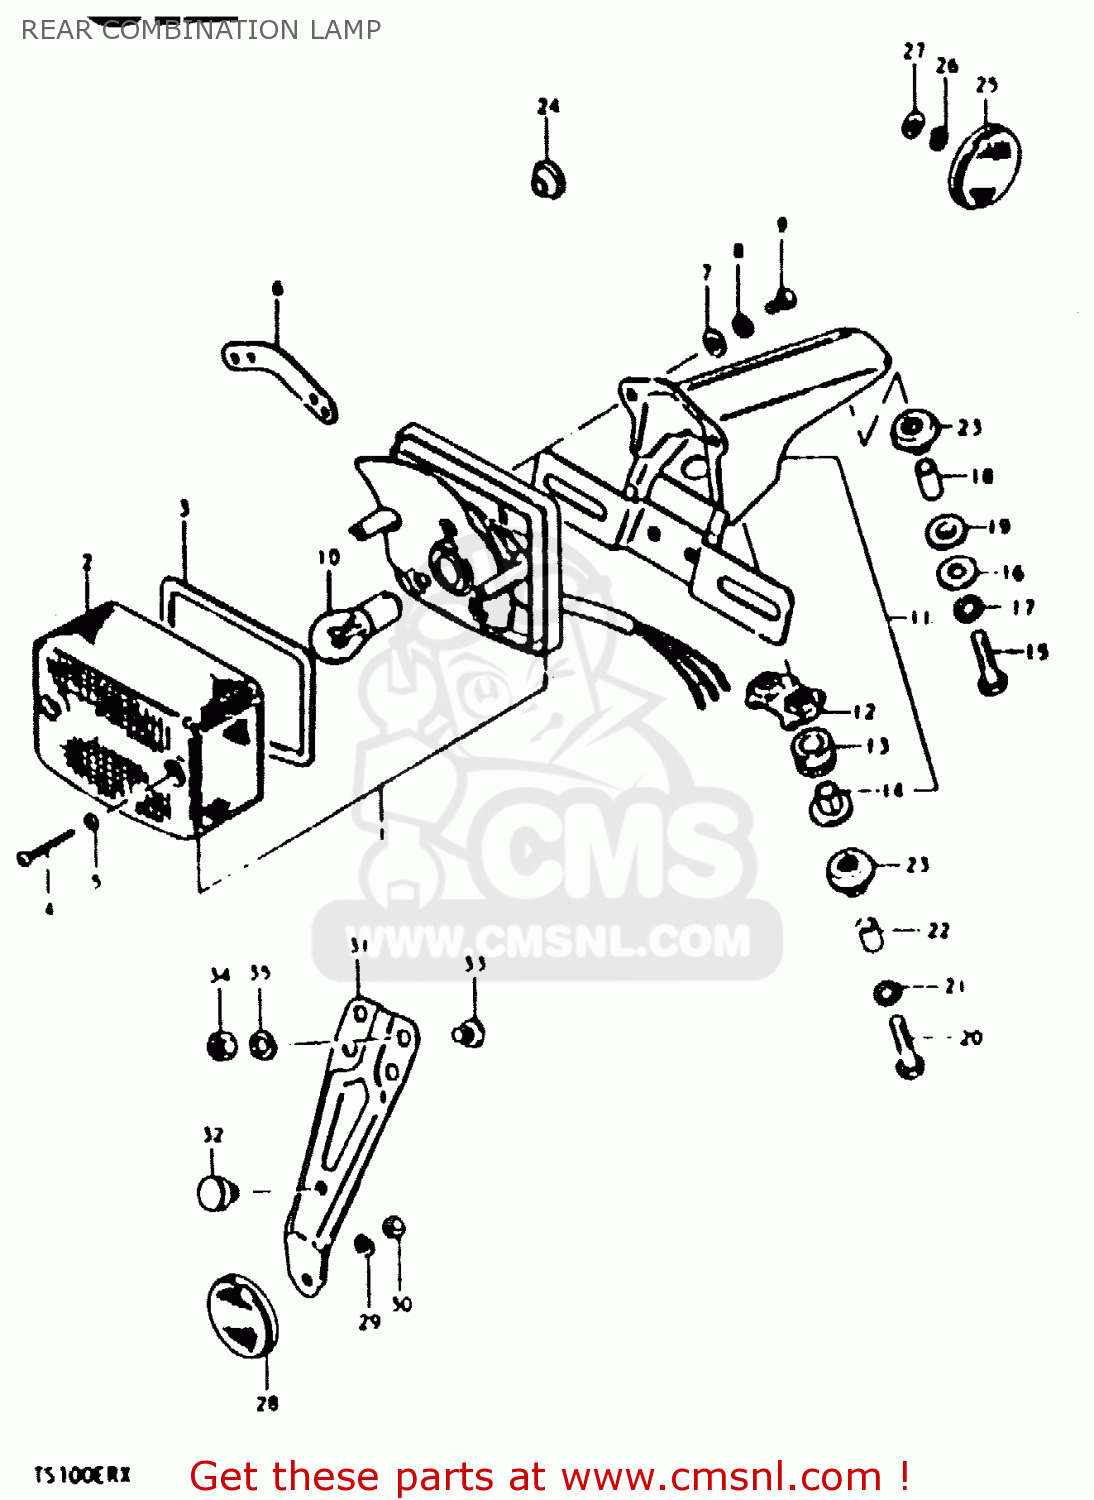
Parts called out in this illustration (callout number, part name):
1	LAMP UNIT,REAR COMBINATION
2	LENS
3	GASKET (NAS)
4	BOLT
5	GASKET (NAS)
6	PLATE,REAR COMBINATION LAMP
7	WASHER
8	LOCK WASHER
9	SCREW
10	BULB(6V10/3W,STANLEY,A4854H)
11	BRACKET UNIT,TAIL LAMP
12	PLATE
13	CUSHION
14	SPACER
15	BOLT
16	WASHER (6.5X20X1.2)
17	LOCK WASHER
18	SPACER
19	CUSHION
20	BOLT 6X40
21	LOCK WASHER
22	SPACER (6.8X10X11.5)
23	CUSHION
24	GROMMET
25	REFLEX REFLECTOR,FR
26	LOCK WASHER
27	WASHER
28	REFLEX REFLECTOR,RR
29	LOCK WASHER
30	NUT
31	BRACKET
32	CUSHION
33	SCREW
34	NUT
35	LOCK WASHER
